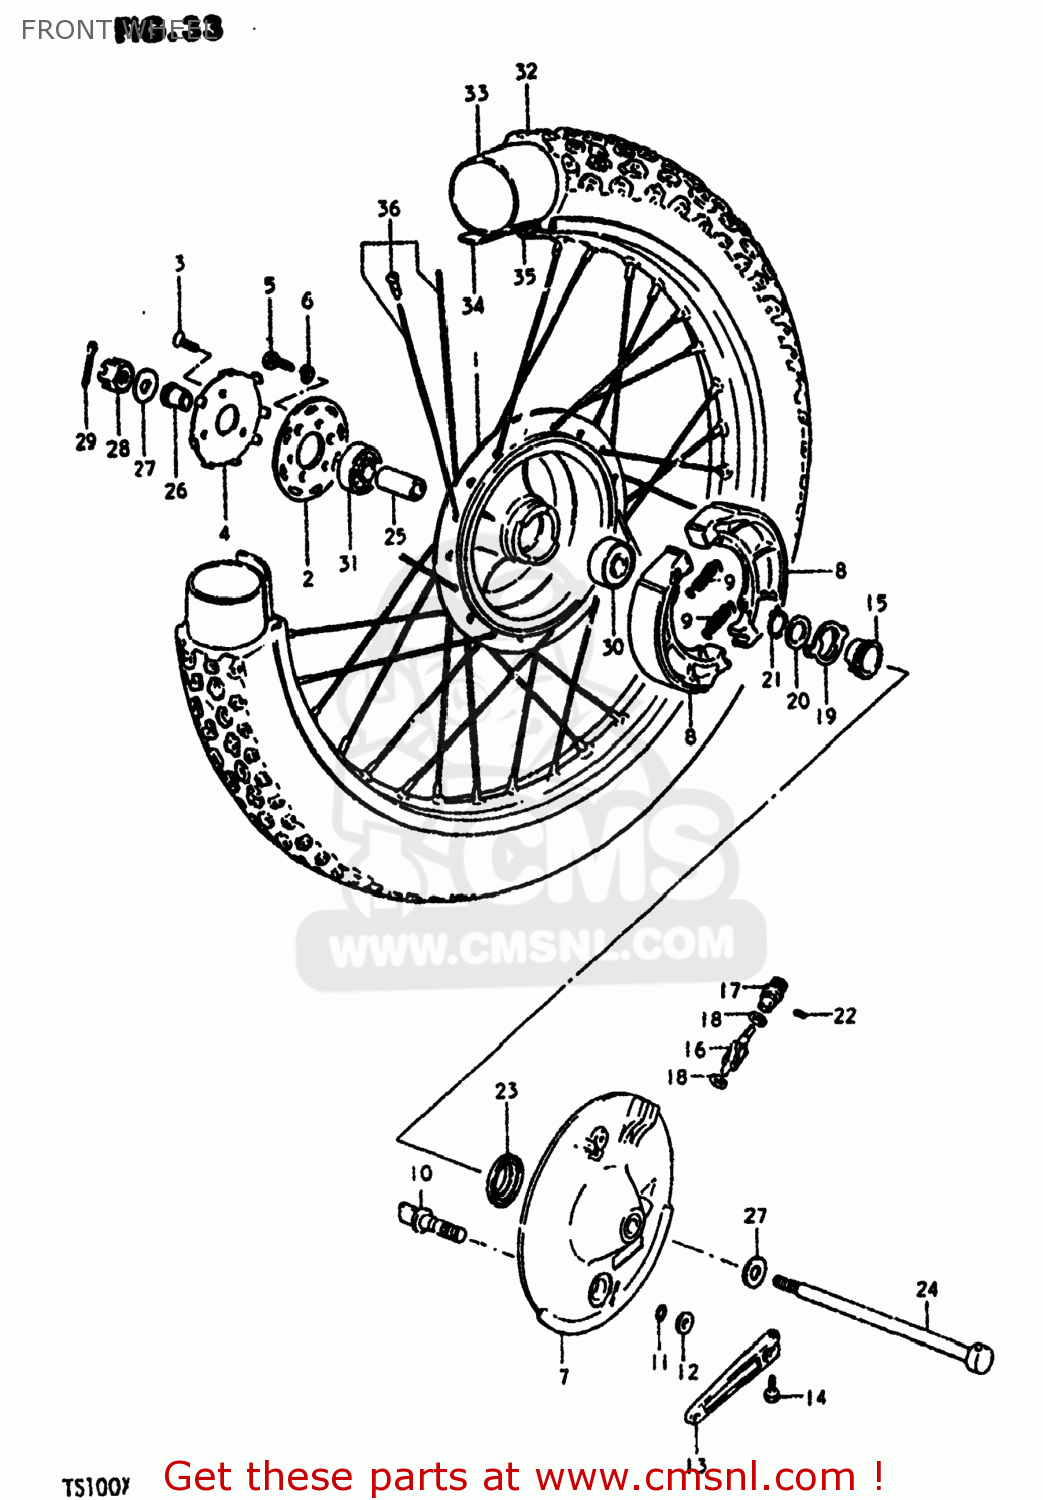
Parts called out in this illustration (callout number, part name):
1	HUB,FR WHEEL
2	FLANGE,FR HUB,R
3	SCREW
4	RETAINER,FR HUB BEARING,R
5	BOLT, UPPER
6	LOCK WASHER
7	PANEL,FRONT HUB
8	SHOE,BRAKE
9	SPRING(L:34)
10	CAM,FRONT BRAKE
11	O-RING (D:2.4 ID:13.8)
12	WASHER (14.5X22X1.6)
13	LEVER,FRONT BRAKE CAM
14	BOLT
15	GEAR,SPEEDOMETER
16	PINION,SPEEDOMETER
17	BUSH,METER GEAR OUTER
18	WASHER (5.1X9X0.4)
19	DRIVER,SPEEDOMETER GEAR
20	WASHER(18.5X24X1)
21	CIRCLIP
22	SCREW
23	OIL SEAL (43X58X7)
24	AXLE,FRONT
25	SPACER (12.6X19X52)
26	SPACER,FR AXLE,R
27	WASHER
28	NUT 12MM
29	COTTER PIN
30	BEARING
31	BEARING, RH
32	TIRE,FRONT
33	TUBE 2.75-19 070-483MM
34	PROTECTOR,WHEEL,INNER
35	RIM,FR WHEEL
36	SPOKE SET,FRONT
